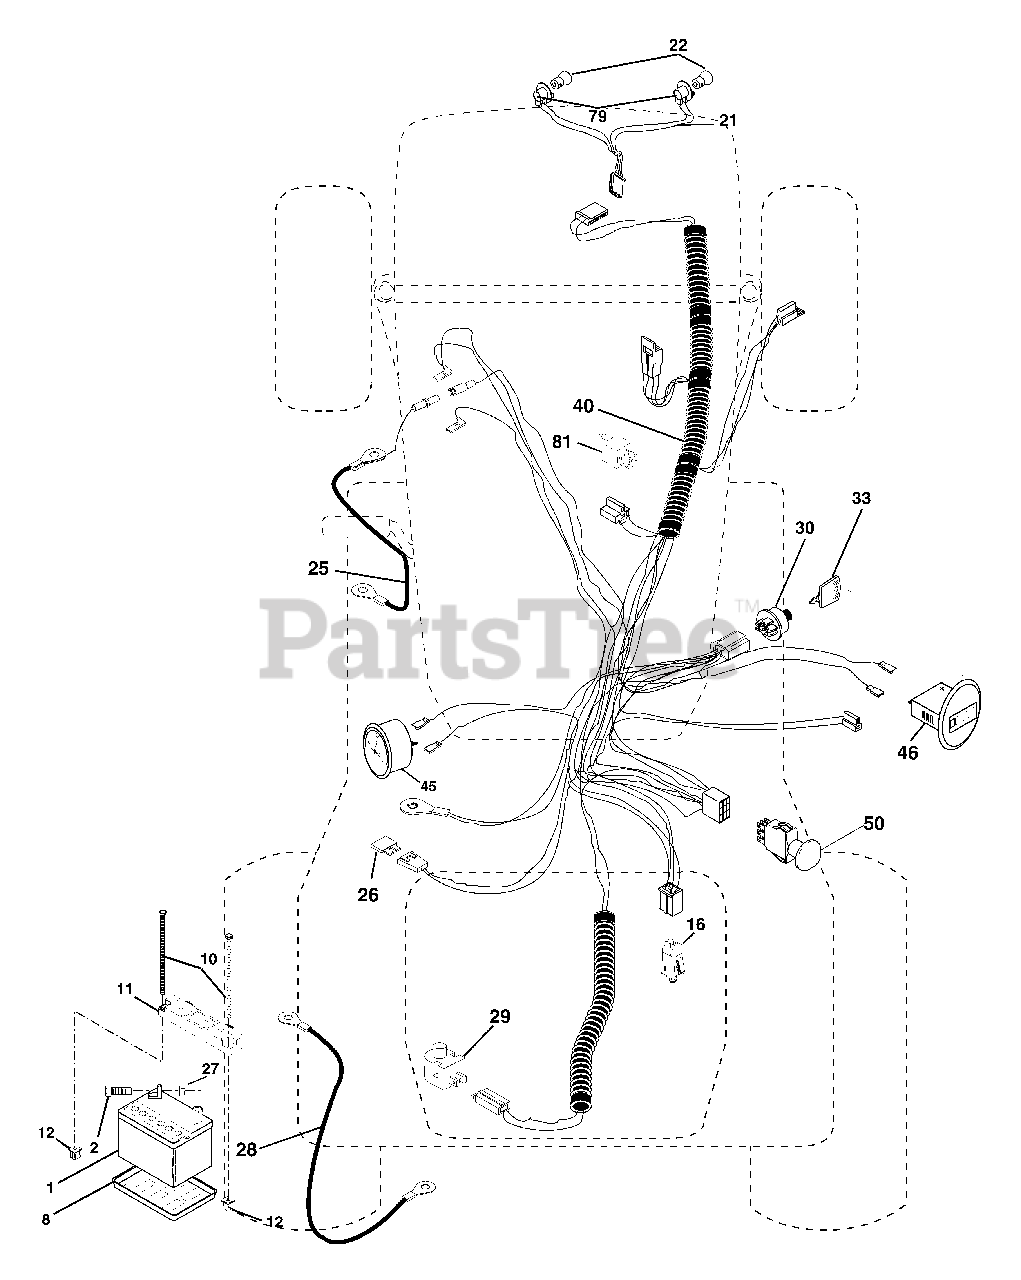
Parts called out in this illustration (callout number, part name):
1	Battery
2	Bolt Hex Head 1/4-20 x 3/4
8	Tray, Battery
10	Bolt, Battery Front 1/4-20 x 7.5 Zinc
11	Holddown Battery Front Mount
12	Nut, Push Nylon 1.4" Battery Front
16	Switch Interlock Push-In
21	Harness Socket Light w/4152J
25	Cable, Battery
27	Nut Keps Hex 1/4-20
28	Cable, Ground
29	Switch, Plunger Normal Op Olive
30	Switch, Ign
40	Harness Ign.
42	Cover, Terminal Red
50	Switch, PTO
79	Socket Assembly Bulb
81	Relay Asm.
